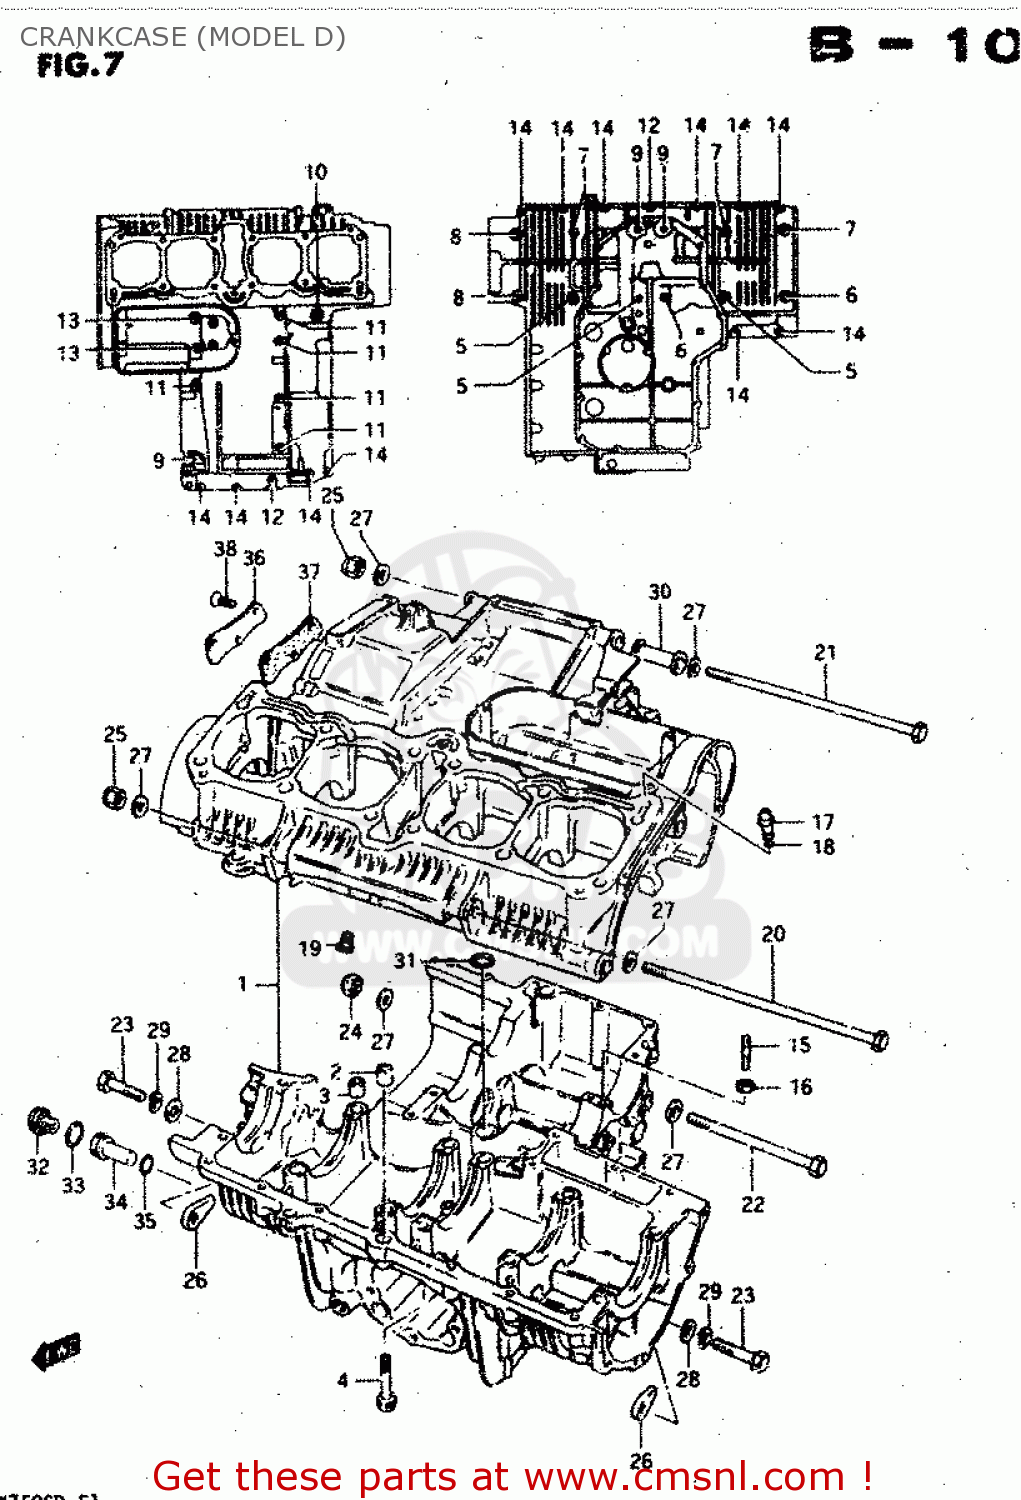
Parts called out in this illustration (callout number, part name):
1	CRANKCASE SET
2	PIN(10.4X13X22)
3	PIN (11X20)(SUS)
4	BOLT
5	BOLT(8X140)
6	BOLT
7	BOLT (8X95)
8	BOLT (8X70)
9	BOLT 8X65
10	BOLT (5X95)
11	BOLT
12	BOLT ,6X60
13	BOLT,UNDER
14	BOLT (6X40)
15	STUD BOLT
16	NUT
17	JET
18	O RING(D:1.05,ID:3.1)
19	JET,AIR
20	BOLT(10X225)
21	BOLT(10X250)
22	BOLT(10X165)
23	BOLT 10X60
24	NUT (10MM)
25	NUT
26	NUT
27	WASHER
28	WASHER (10.5X20X3.2)
29	LOCK WASHER
30	SPACER
31	O RING(D:3.2,ID:12.9)
32	PLUG
33	O RING(D:2.4,ID:17.8)
34	PIN,OIL GALLERY
35	SEAL (D:1.9 ID:9.8)
36	CAP,OIL GALLERY
37	GASKET,OIL GALLERY (MCA)
38	SCREW
